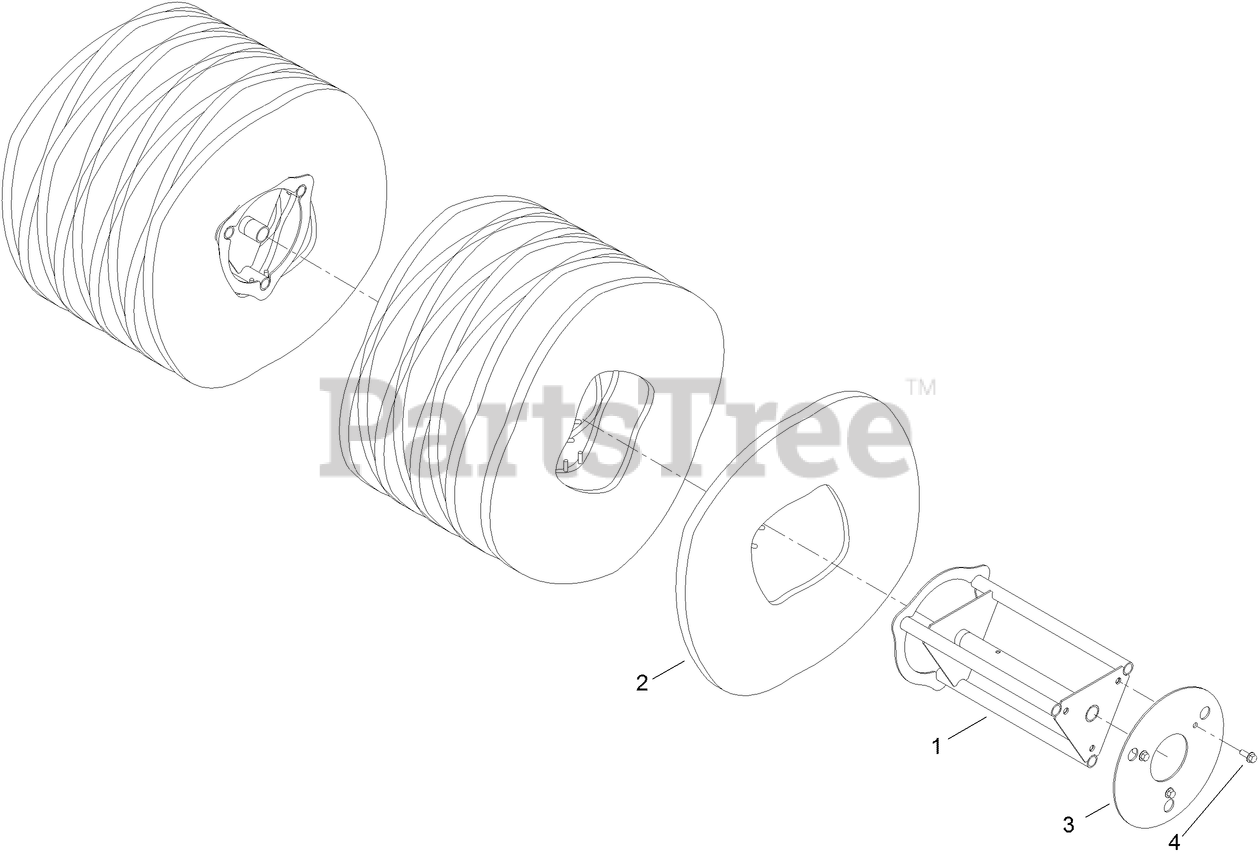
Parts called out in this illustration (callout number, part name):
1	CORE-BROOM
2	SEGMENT-POLY
3	PLATE-END, RETAINER
4	SCREW-HHF
